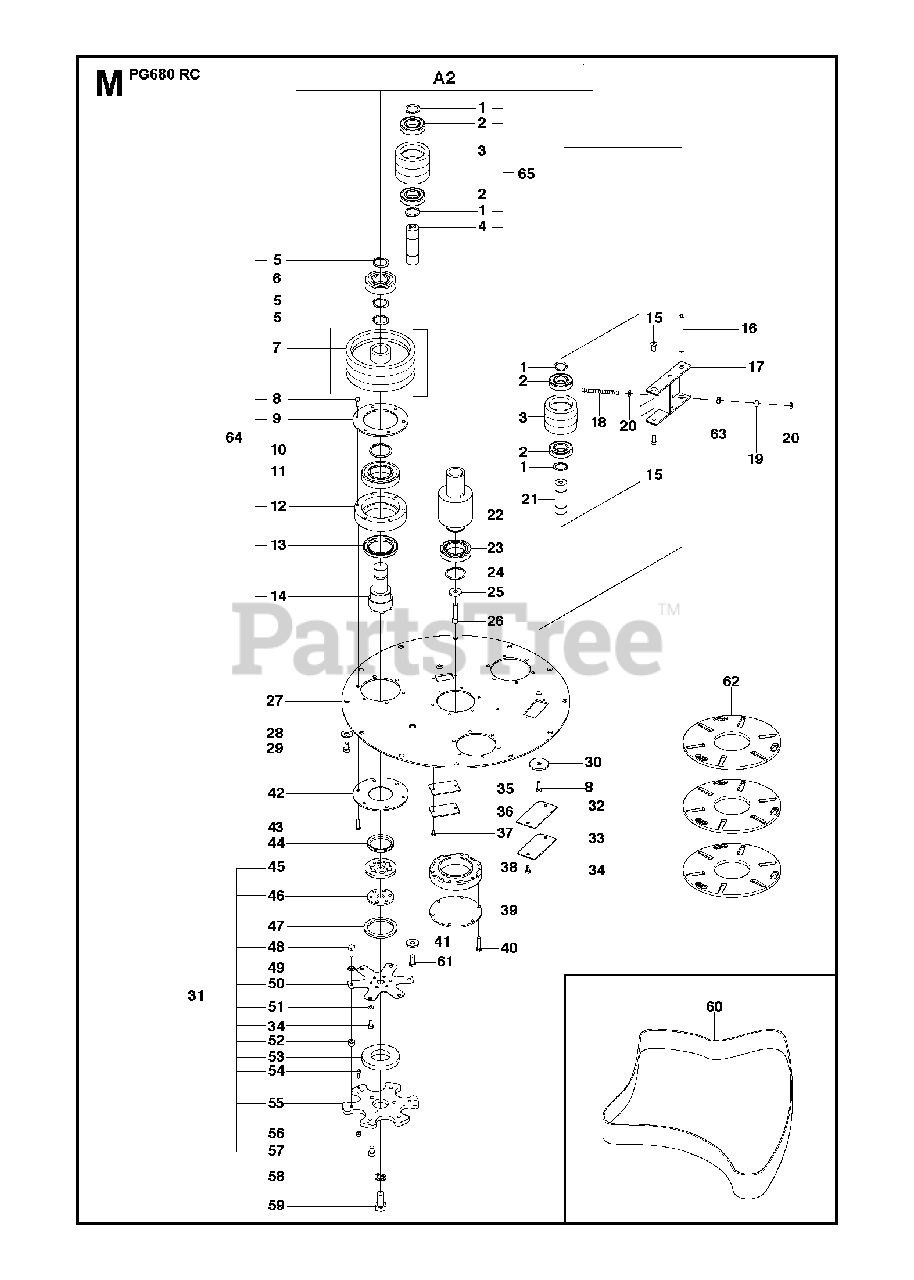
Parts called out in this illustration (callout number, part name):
20	WASHER
28	WASHER
34	SCREW EHHM
49	WASHER
51	WASHER
63	HEXAGON LOCKING NUT
